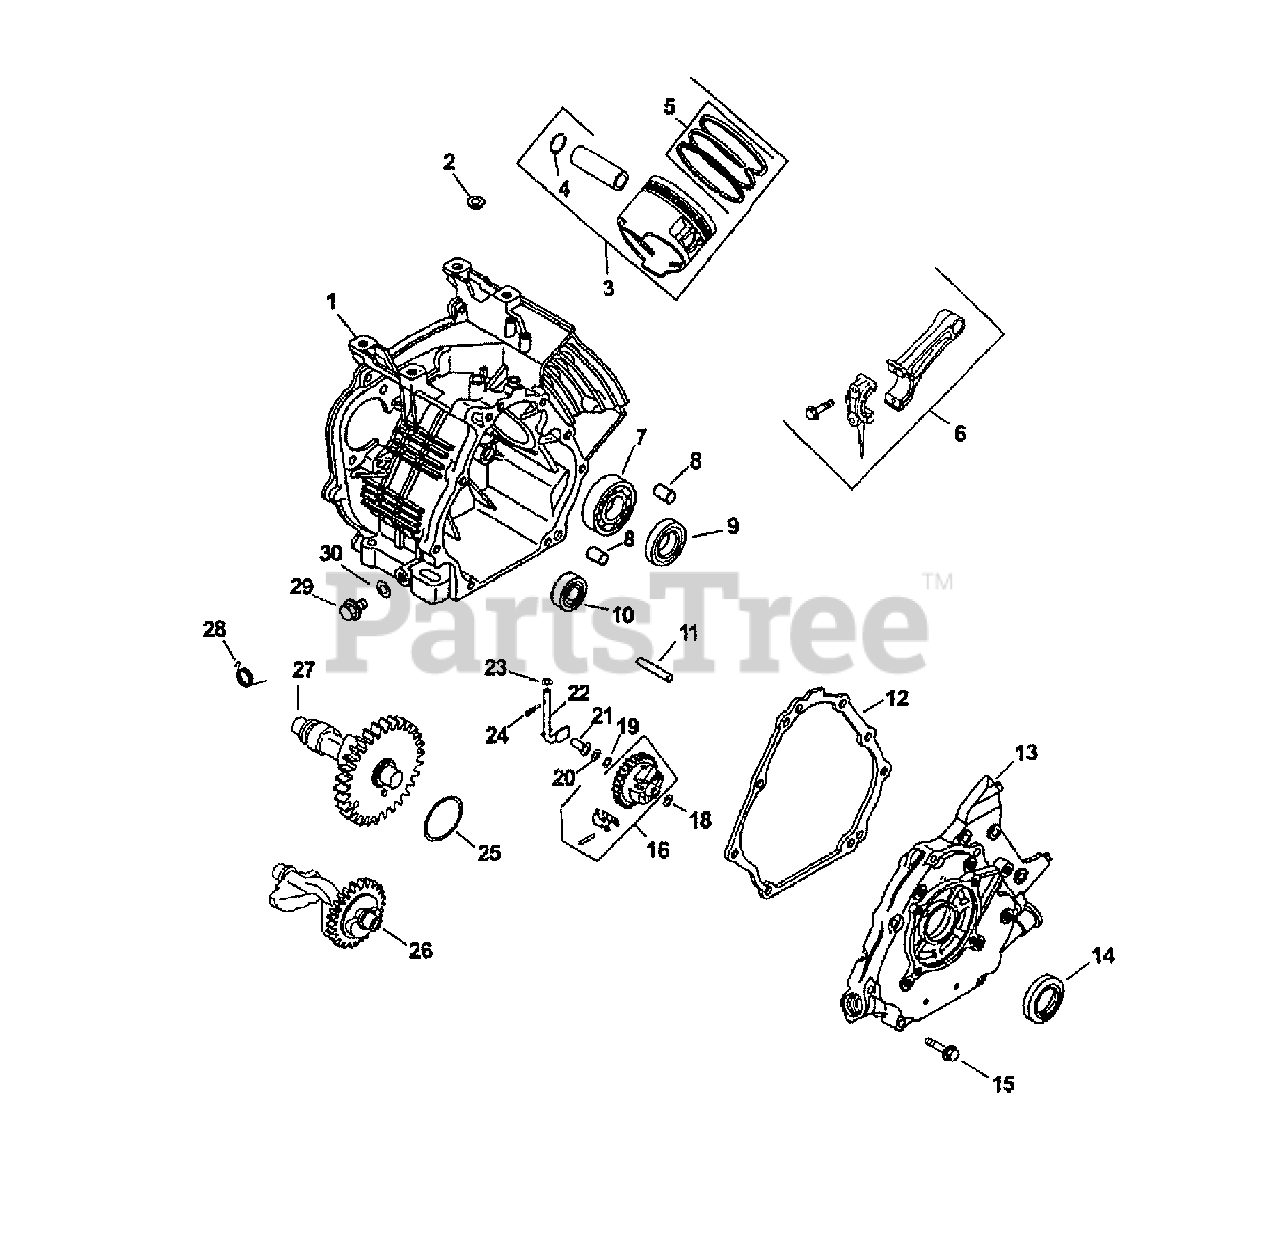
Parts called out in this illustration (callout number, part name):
2	Seal, Governor Shaft
3	Piston w/Ring std.
4	Retainer, Piston Pin
5	Ring Set std.
6	Rod Connecting
11	Shaft, Governor
12	Gasket, Closure Plate
13	I Plate, Closure
15	Screw, Closure Plate
16	Governor Gear
20	Washer, Air Cleaner
22	Shaft, Governor
26	Shaft, Balance
